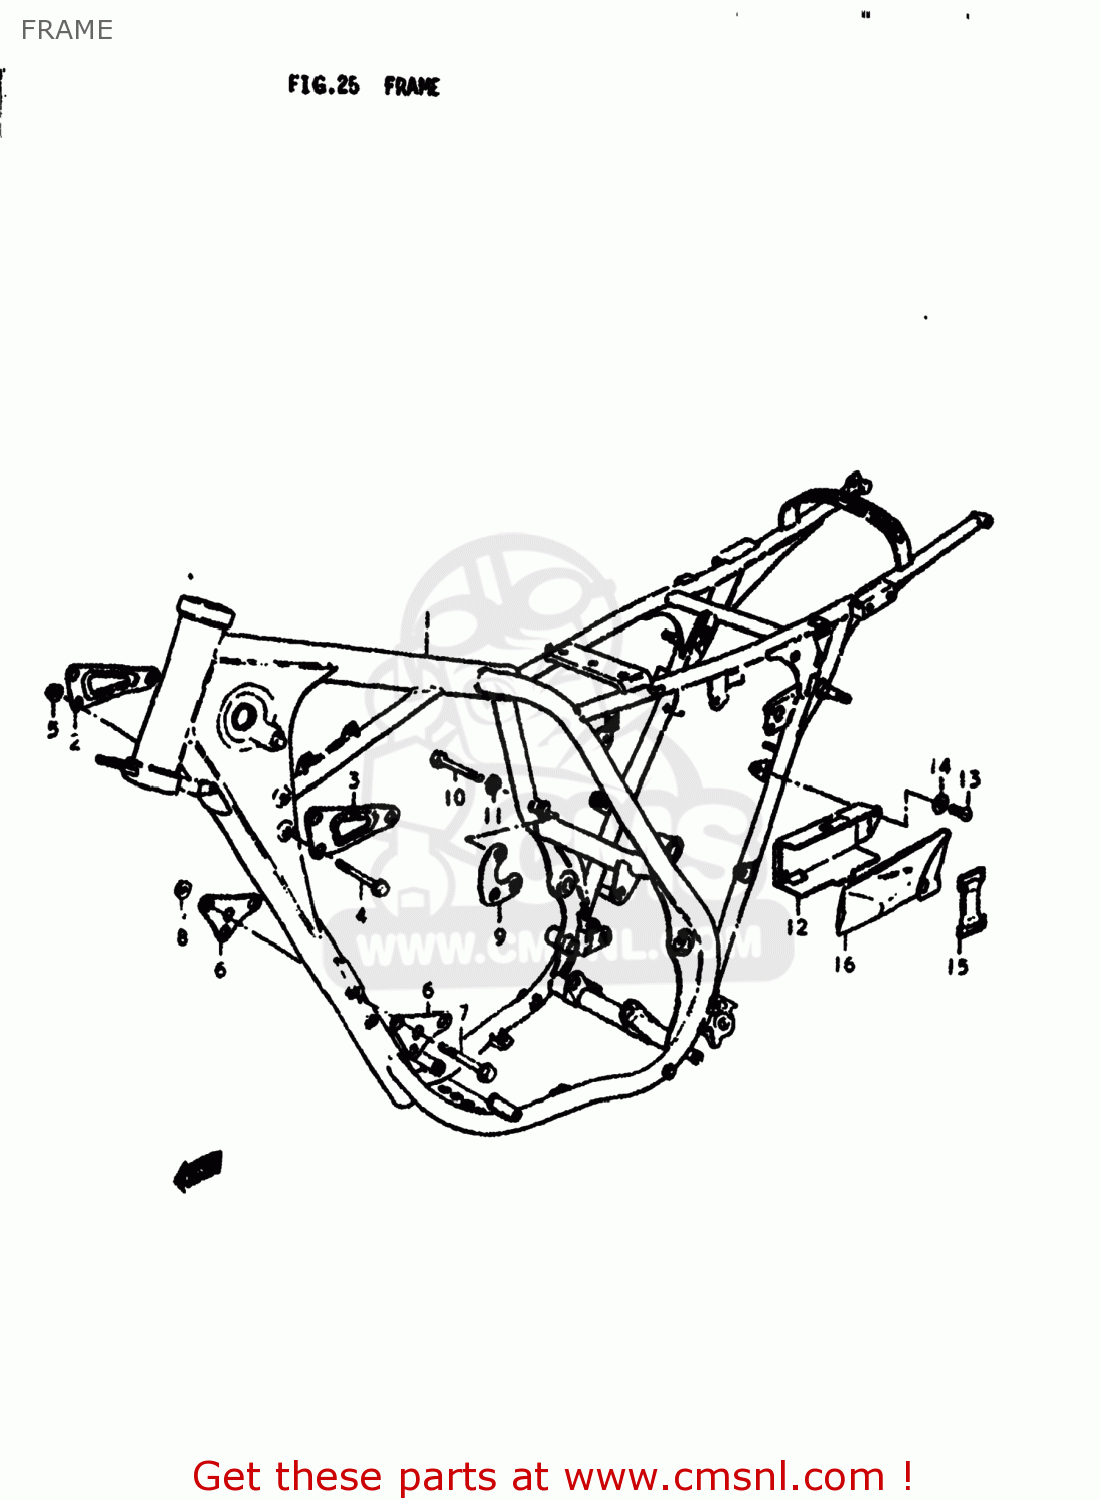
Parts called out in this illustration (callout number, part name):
1	FRAME
2	PLATE,ENGINE MOUNTING
3	PLATE,ENGINE MOUNTING
4	BOLT (6X70)
5	NUT
6	PLATE,ENGINE MOUNTING
7	BOLT (8X70)
8	NUT
9	PLATE,ENGINE MOUNTING
10	BOLT
11	LOCK WASHER
12	HOLDER,TOOL
13	SCREW
14	WASHER 6MM
15	BAND
16	TOOL SET
